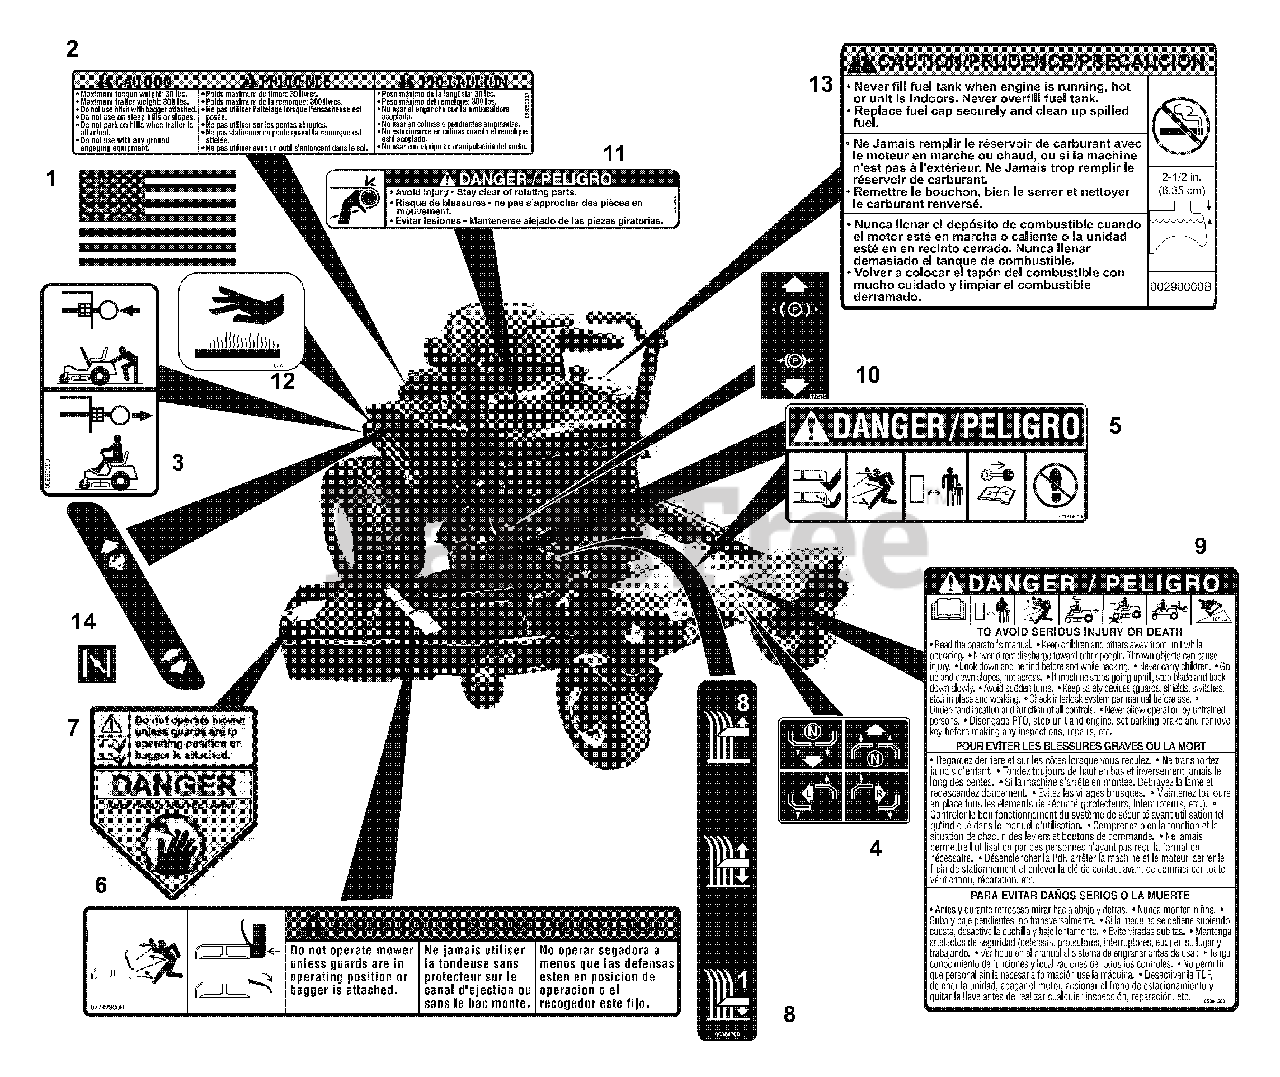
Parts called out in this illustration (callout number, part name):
1	DECAL, AMERICAN FLAG
2	DECAL, TRAILER HITCH
3	DECAL, TRANSMISSION DISCONNECT
4	DECAL, INSTRUCTIONAL-STEERING
5	DECAL, MOWER PAN DANGER
6	DECAL, WARNING
7	DECAL, CPSC DANGER
8	DECAL,CUT HEIGHT
9	DECAL, DANGER BILINGUAL
10	DECAL, PARKING BRAKE LEVER
11	DECAL- DANGER
12	DECAL, HOT SURFACE
13	DECAL,FUEL WARNING
14	DECAL, SPEED CONTROL
